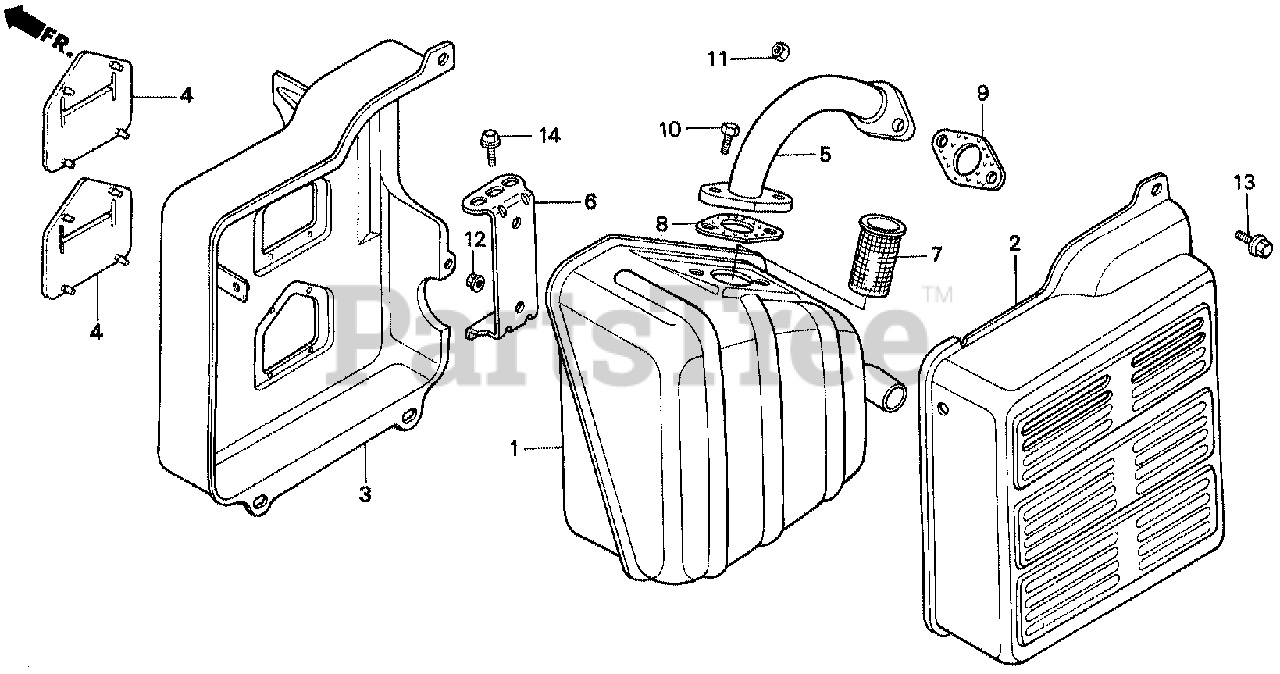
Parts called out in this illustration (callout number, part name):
1	MUFFLER
2	PROTECTOR, MUFFLER (OUTER)
3	PROTECTOR, MUFFLER (INNER)
4	SEAL, MUFFLER PROTECTOR
5	PIPE, EX.
6	STAY, MUFFLER
7	ARRESTER, SPARK
8	GASKET, MUFFLER
9	GASKET, MUFFLER
10	BOLT, HEX. (8X20)
11	NUT, HEX. (8MM)
12	NUT, FLANGE (6MM)
13	BOLT, FLANGE (6X12)
14	BOLT, FLANGE (8X20)
